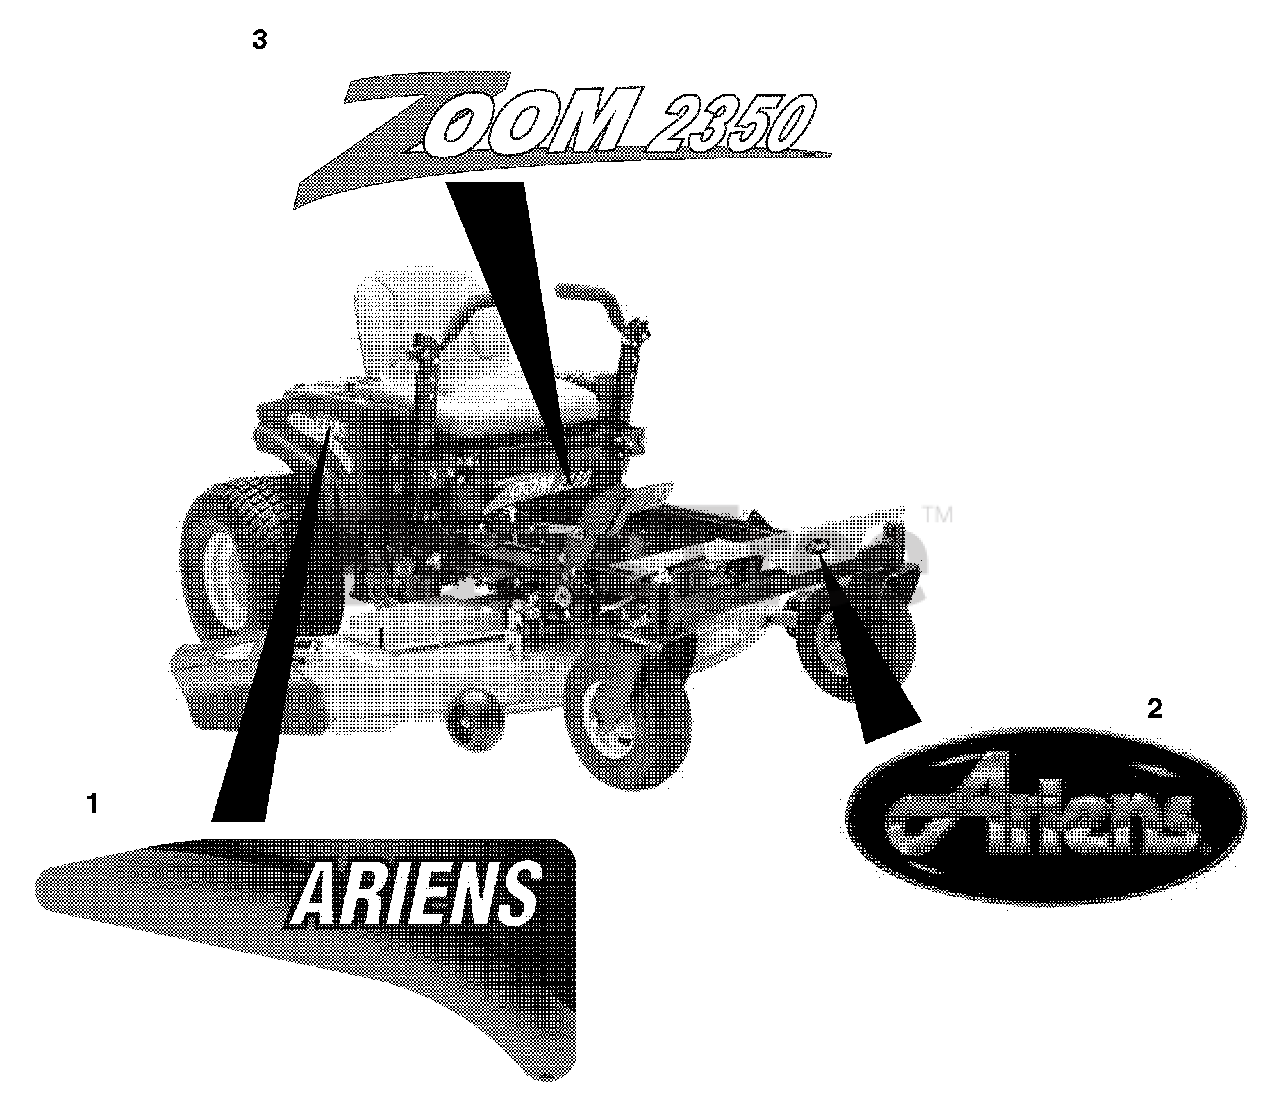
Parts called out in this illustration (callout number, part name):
1	DECAL, RH ARIENS ZOOM TANK
2	DECAL-ARIENS JEWEL
3	DECAL, 2350 ZOOM
